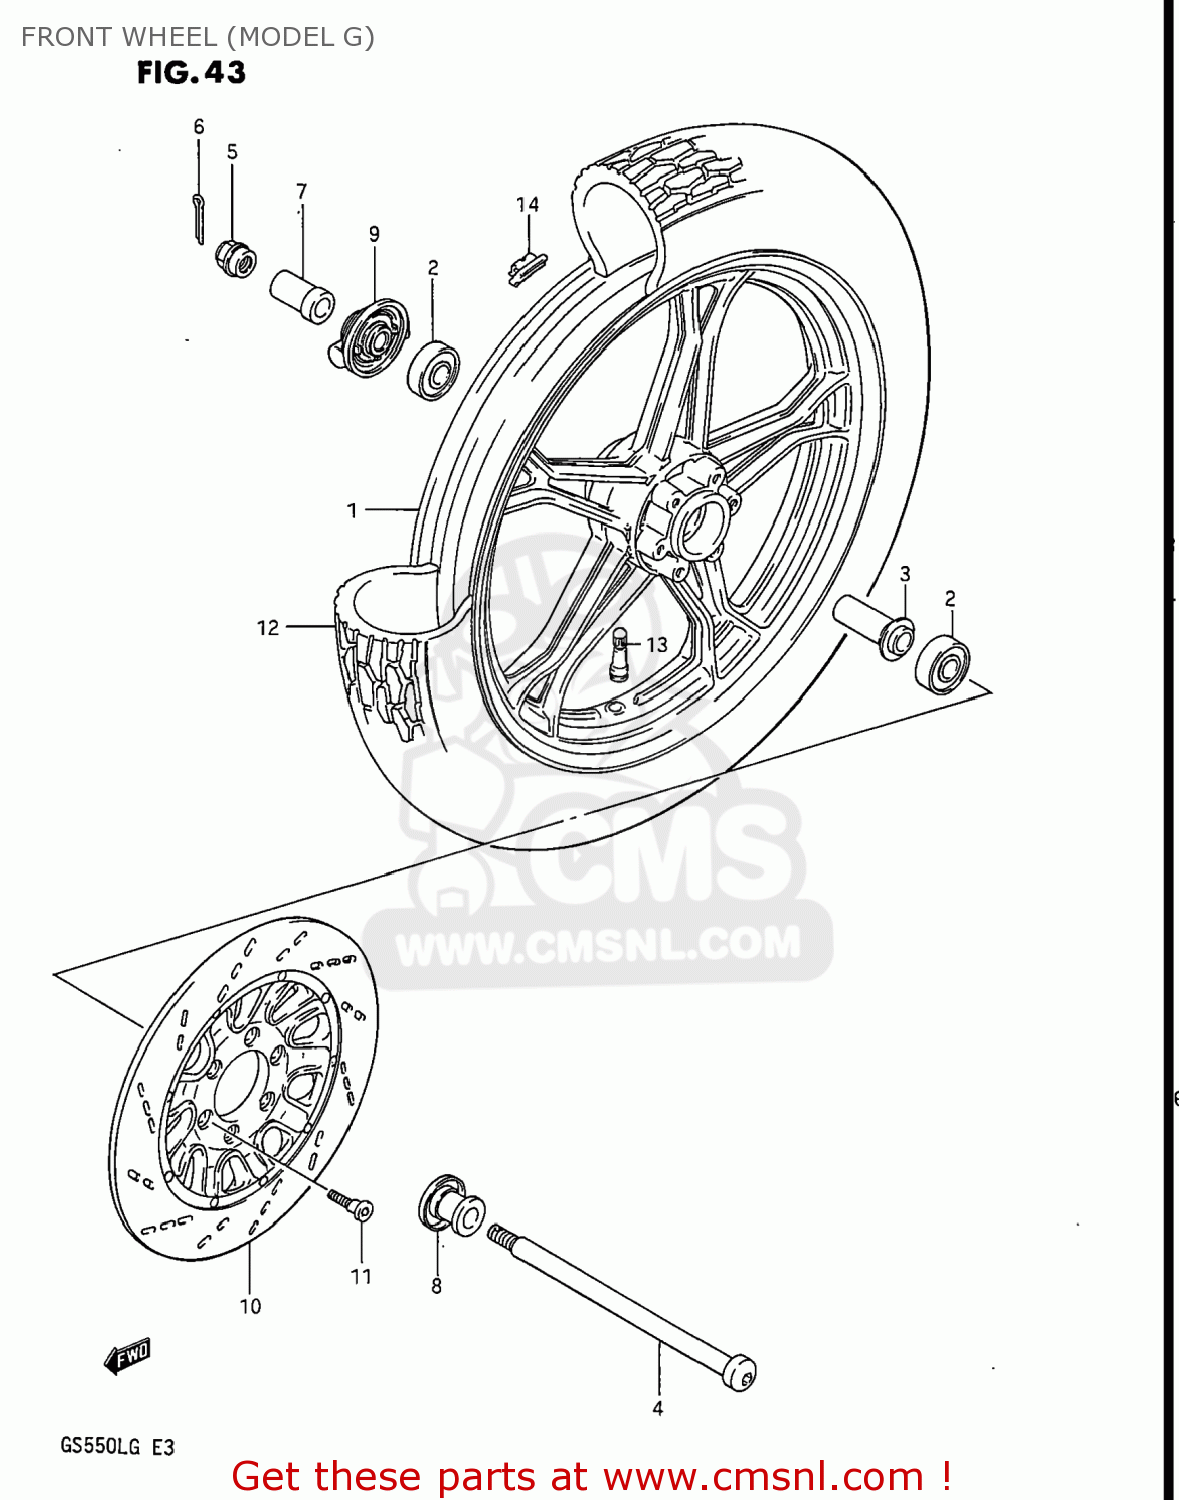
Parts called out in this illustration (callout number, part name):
1	WHEEL,FRONT (MT1.85X19)
2	BEARING
3	SPACER,FRONT HUB BEARING
4	AXLE,FRONT
5	NUT
6	PIN 25X20
7	SPACER,FRONT AXLE,RIGHT
8	SPACER,FRONT AXLE,LEFT
9	BOX ASSY,SPEEDOMETER GEAR
10	DISC,BRAKE
11	BOLT
12	TIRE,FRONT
13	VALVE,TIRE
14	BALANCER,WHEEL
